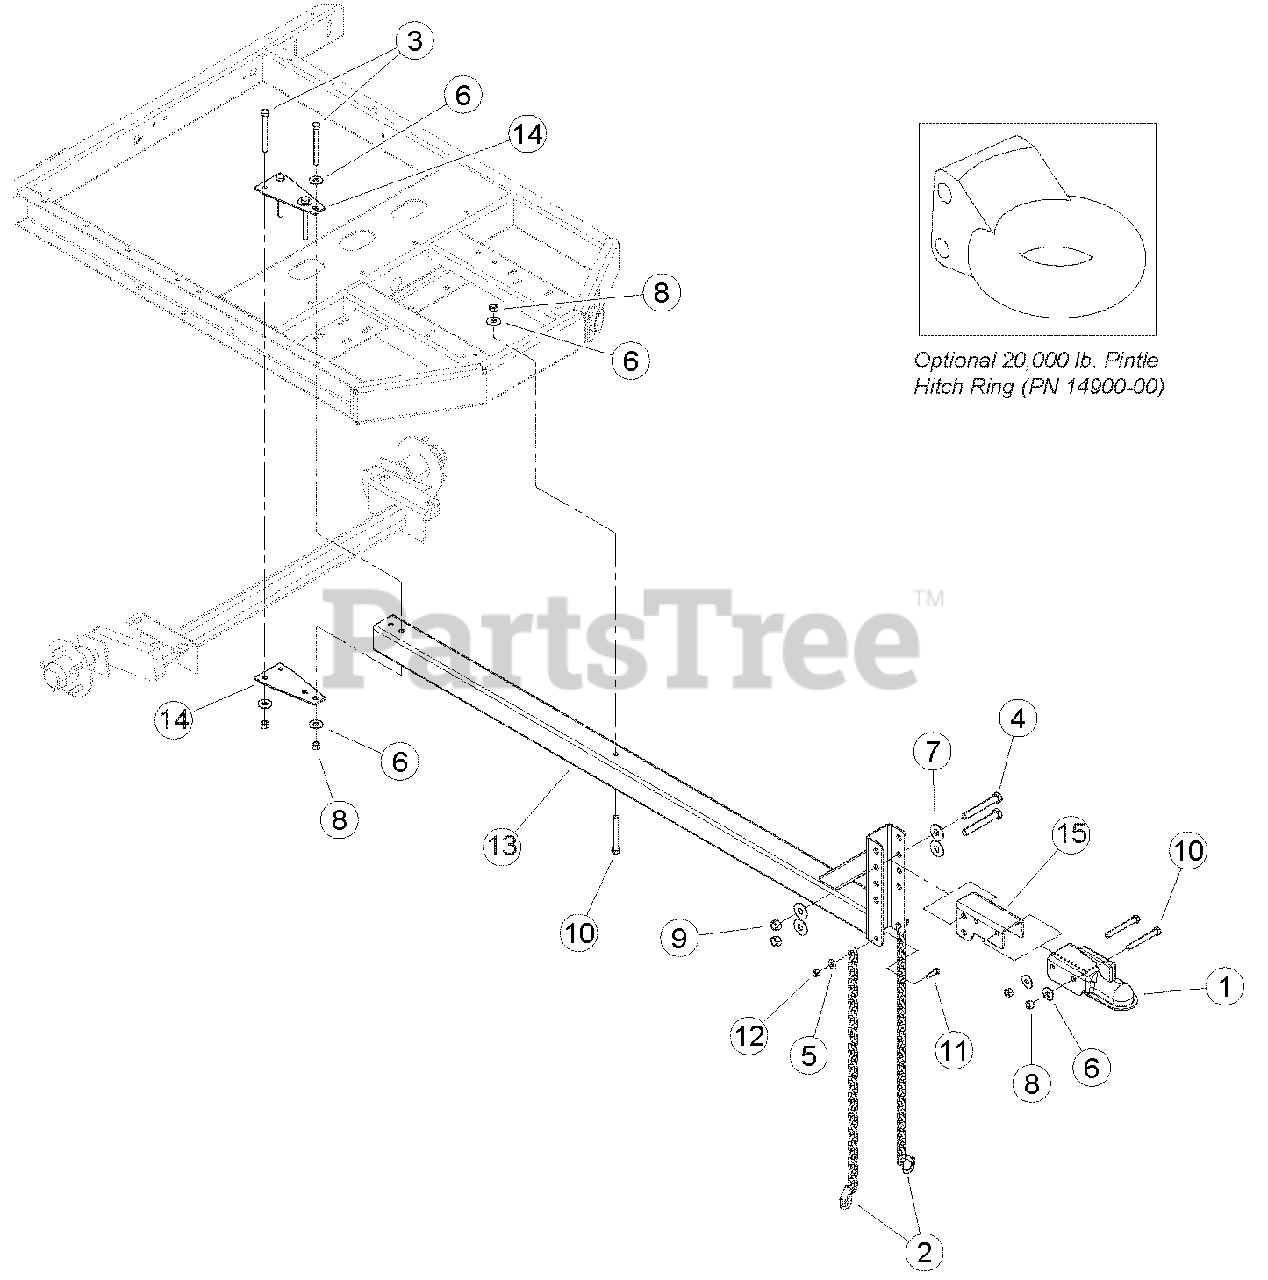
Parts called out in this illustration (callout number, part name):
1	COUPLER, 2 IN
2	CHAIN, SAFETY, 5000 LB W/LATCH
3	BOLT, 1/2 X 4-1/2 HEX HD GR5
4	BOLT, 5/8 X 4-1/2 HEX HD GR5
5	WASHER, 3/8 FLAT ZP
6	WASHER, 1/2 FLAT ZP
7	WASHER, 5/8" FLAT ZP-37PCS/LB
8	NUT, 1/2 CENTERLOCK GRB ZP
9	NUT, 5/8 CENTERLOCK
10	BOLT 1/2 X 4 HEX HD GR5 ZP
11	BOLT, 3/8 X 1-1/4 HEX HD GR5 ZP
12	NUT, 3/8 NYLOCK
13	WELDMENT, HITCH POLE
14	PLATE, AXLE SAFETY
15	MOUNT, COUPLER
